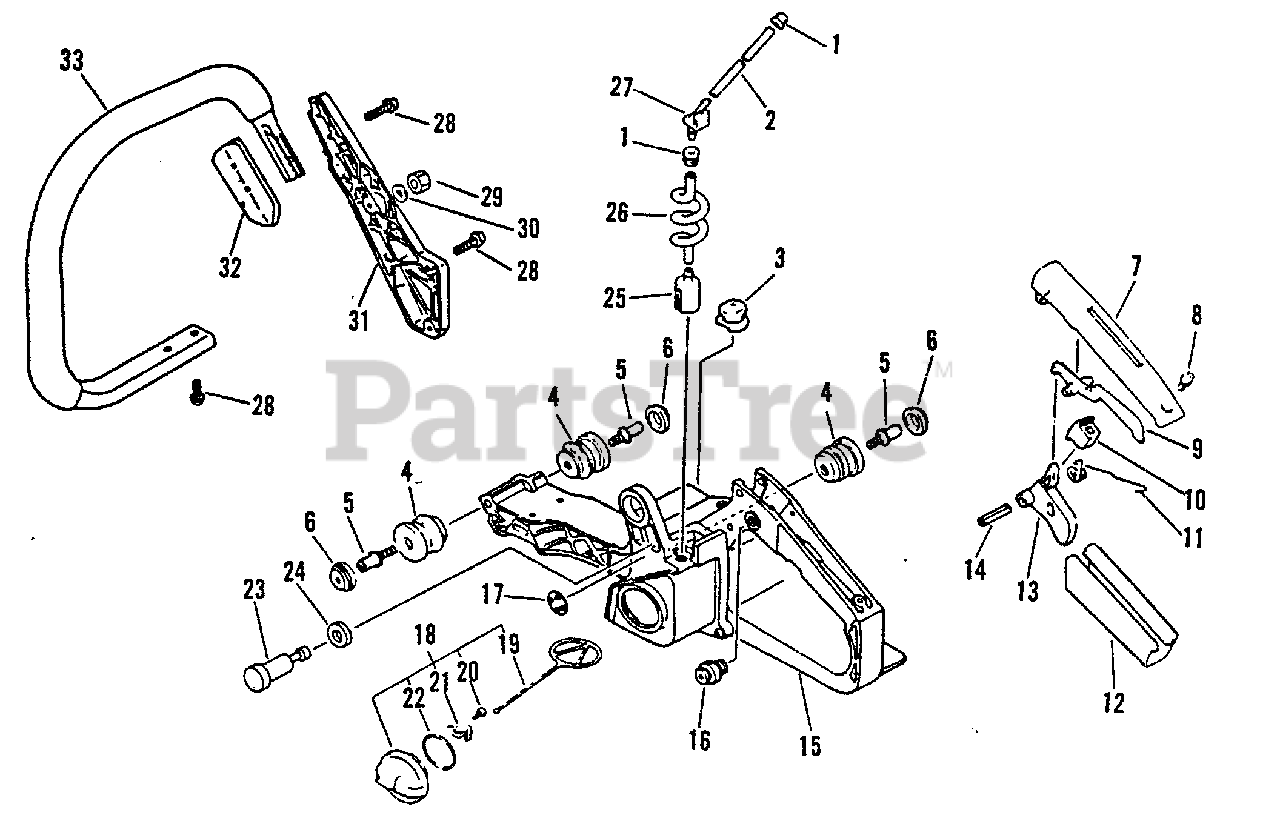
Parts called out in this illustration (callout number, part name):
1	GROMMET
2	PIPE - 3X6X100 -- BLACK
4	CUSHION
6	CAP, CUSHION
7	COVER, HANDLE
8	SCREW - 4X14
9	LEVER, TRIGGER LOCKOUT
11	SPRING, TRIGGER
12	GRIP, HANDLE
13	TRIGGER, THROTTLE
14	PIN - SPRING -- 5X25
15	HANDLE - REAR
16	LOCK, THROTTLE
18	CAP ASSY
19	CONNECTOR, CAP
20	SCREW - 3X8
21	RETAINER
22	O-RING - 29
23	VENT, FUEL TANK
24	GROMMET
25	FILTER, FUEL
26	PIPE, FUEL - SPIRAL
27	CONNECTOR, PIPE
28	SCREW - 5X20
29	NUT - 5 -- SLOTTED
30	WASHER - 5
31	BRACKET, HANDLE - OUTER
32	BRACKET, HANDLE
33	HANDLE - FRONT
